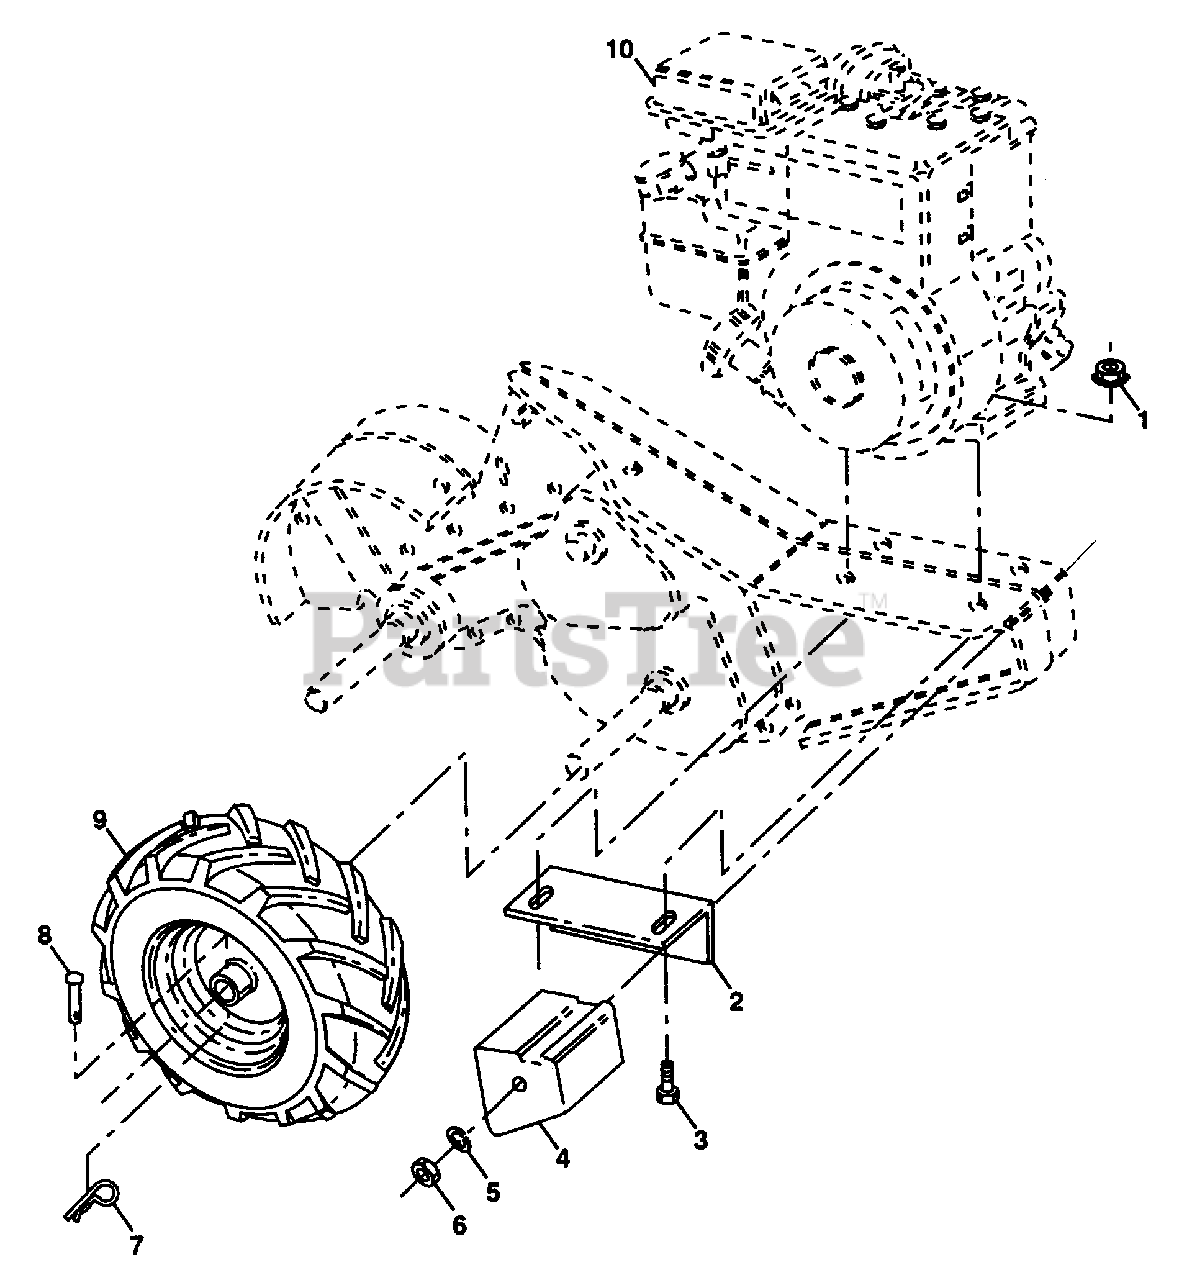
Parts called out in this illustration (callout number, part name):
1	Nut, Keps 5/16-18 (AYP part number)
2	Bracket, Reinforcment (AYP part number)
3	Bolt, Hex 5/16-18 x 1-1/2 (AYP part number)
4	Counter Weight, R.H. (AYP part number)
5	Washer, Lock 3/8 (AYP part number)
6	Nut, Hex 3/8-16 (AYP part number)
7	Clip, Hairpin (AYP part number)
8	Rivet, Drilled (AYP part number)
9	Tire (AYP part number)
